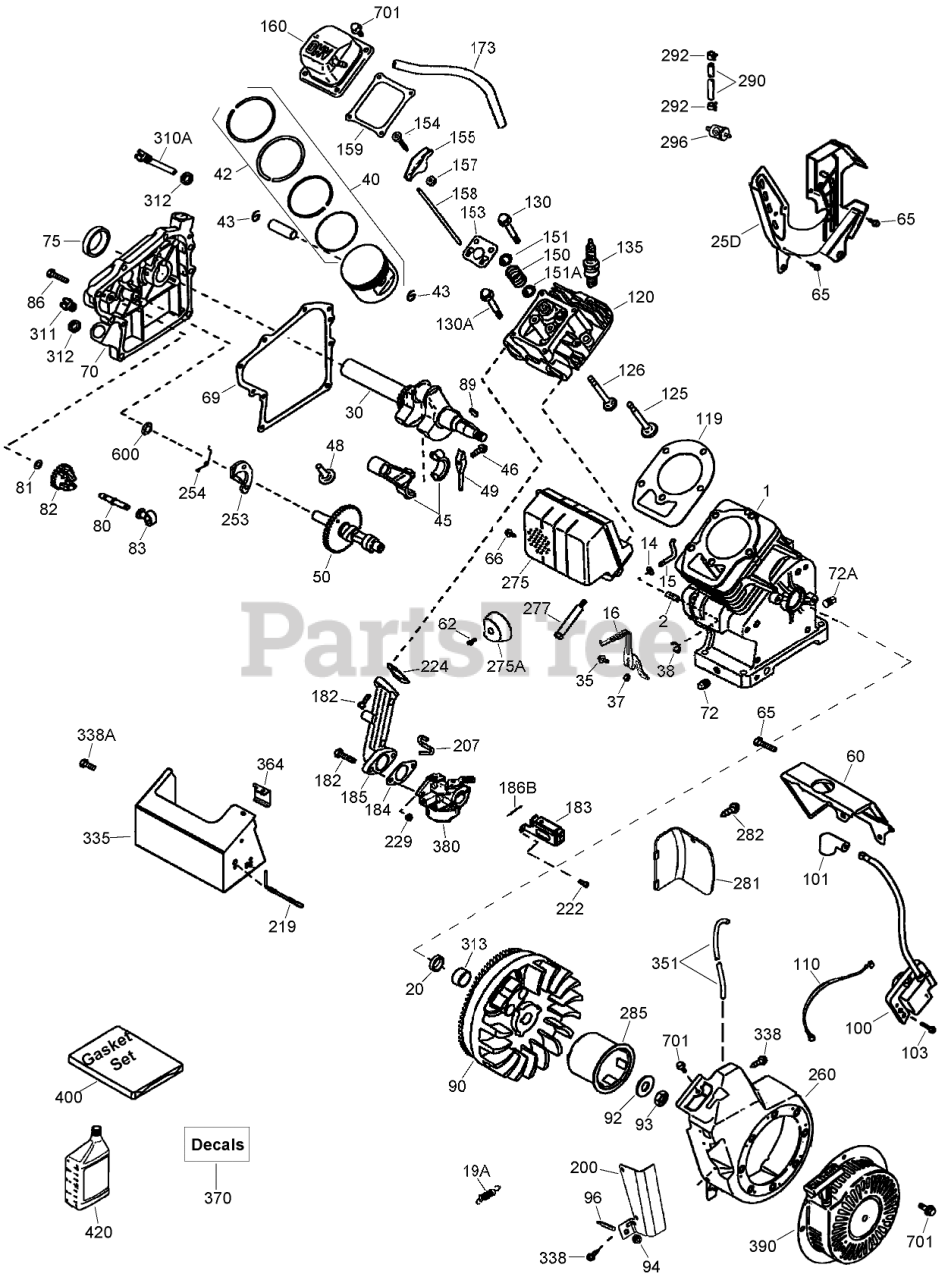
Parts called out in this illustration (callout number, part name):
1	Cylinder ASM (Includes 2, 20, 72, 72A)
2	Pin-Dowel
14	Washer
15	Rod-Governor (Includes 38)
16	Lever-Governor
19A	Spring-Governor
20	Seal-Oil
25D	Baffle-Air
30	Crankshaft
35	Screw (T-25, 10-32 X 63/64)
37	Nut-Square
38	Ring-Retaining
40	Piston, Pin and Ring Set (.010 O S) (Includes 41, 42, 43)
40	Piston, Pin and Ring Set (Std) (Includes 41, 42, 43)
42	Ring Set (.010 O S)
42	Ring Set (STD)
43	Ring-Retaining, Piston Pin
45	Connecting Rod Asm (Includes 46, 49)
46	Bolt-Rod, Connecting
48	Lifter-Valve
49	Dipper-Oil
50	Camshaft (Includes 150, 253, 254)
60	Extension-Housing, Blower
62	Screw (8-32 x 3/8)
65	Screw (10-24 x 9/16)
66	Screw (1/4-20 x 27/32)
69	Gasket-Cover, Cylinder
70	Cover-Cylinder (Includes 75-83, 311)
72	Plug-Drain, Oil (SQH 1/4-18)
72A	Plug-Pipe (Internal Hex, 1/4-18)
75	Seal-Oil
80	Shaft-Governor
81	Washer-Flat
82	Governor Gear ASM (Includes 81)
83	Spool-Governor
86	Screw (1/4-20 x 1-1/4)
89	Key-Flywheel
90	Flywheel (Cast Iron)
92	Washer-Belleville
93	Nut-Flywheel
94	Nut (10-32)
96	Bolt-Adjusting, R.P.M.
100	Ignition-State, Solid
101	Cover-Spark Plug
103	Screw (T-15, 10-24 x 15/16)
110	Wire-Ground
119	Gasket-Head, Cylinder
120	Head-Cylinder (Includes 151A)
125	Valve-Exhaust (1/32 O S) (Includes 151)
125	Valve-Exhaust (STD) (Includes 151)
126	Valve-Intake (STD) (Includes 151, 151A)
130	Screw (5/16-18 x 1-1/2)
130A	Screw (5/16-18 x 2-41/64)
